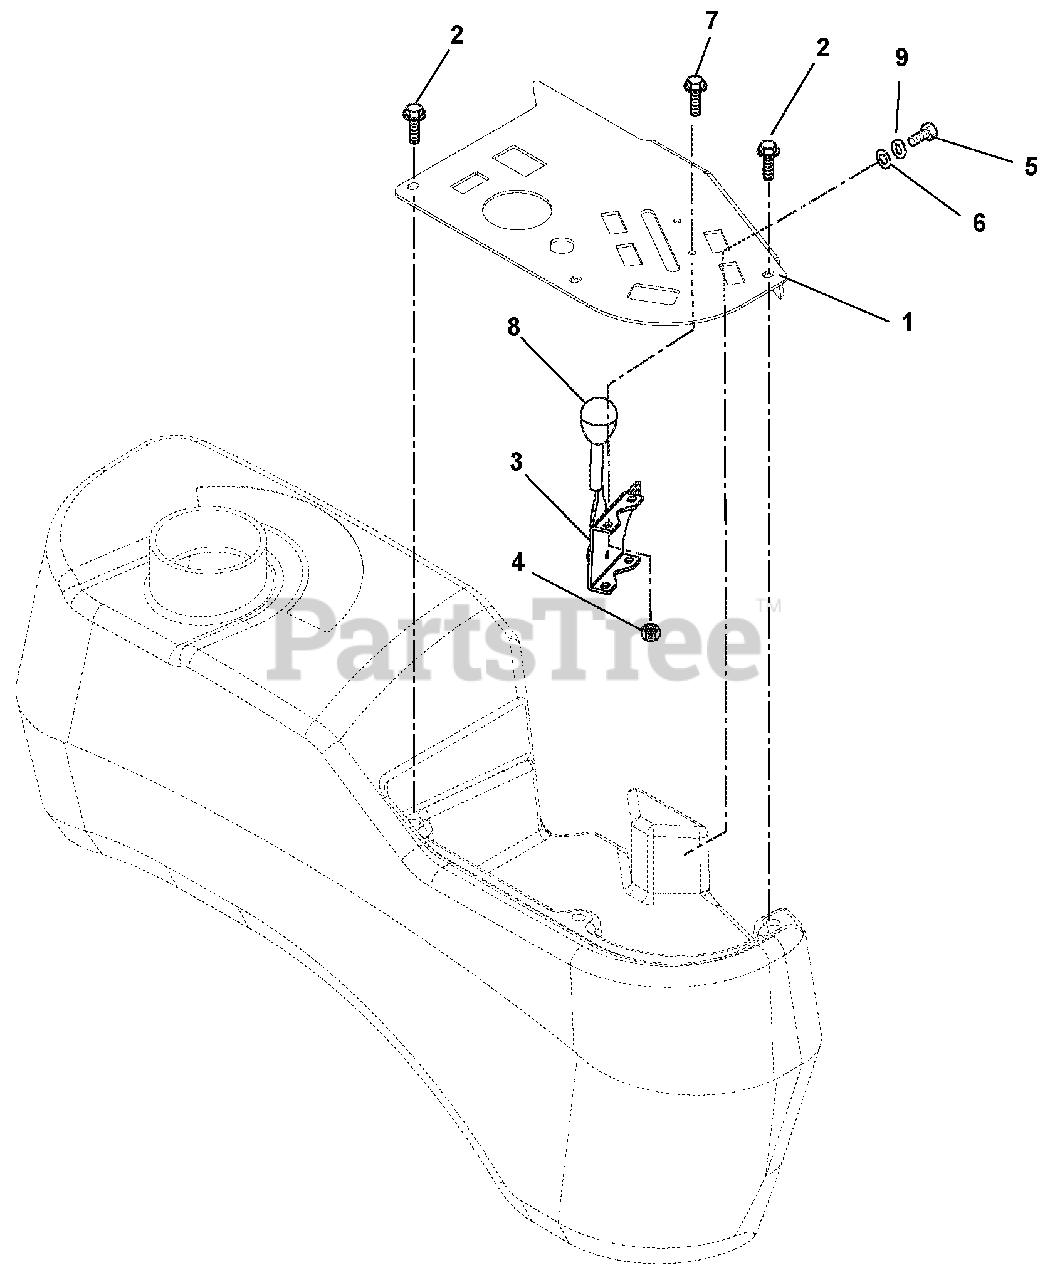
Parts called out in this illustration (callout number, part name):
1	Panel, Control
2	Screw, Machine Hex Washer Head 10-24 x .38 Stainless
3	Throttle, Control (Includes item # 8)
4	Nut, Locking Nylon 10-24 with Insert
5	Bolt, Hex .31-18 x .75 Grade 5
6	Washer, Flat Steel .38 x .875 x .083
7	Screw, Machine Hex Washer Head 10-24 x .50
8	Knob, Control, Black .38-16 x .62
9	Washer, Locking .318 x .078
